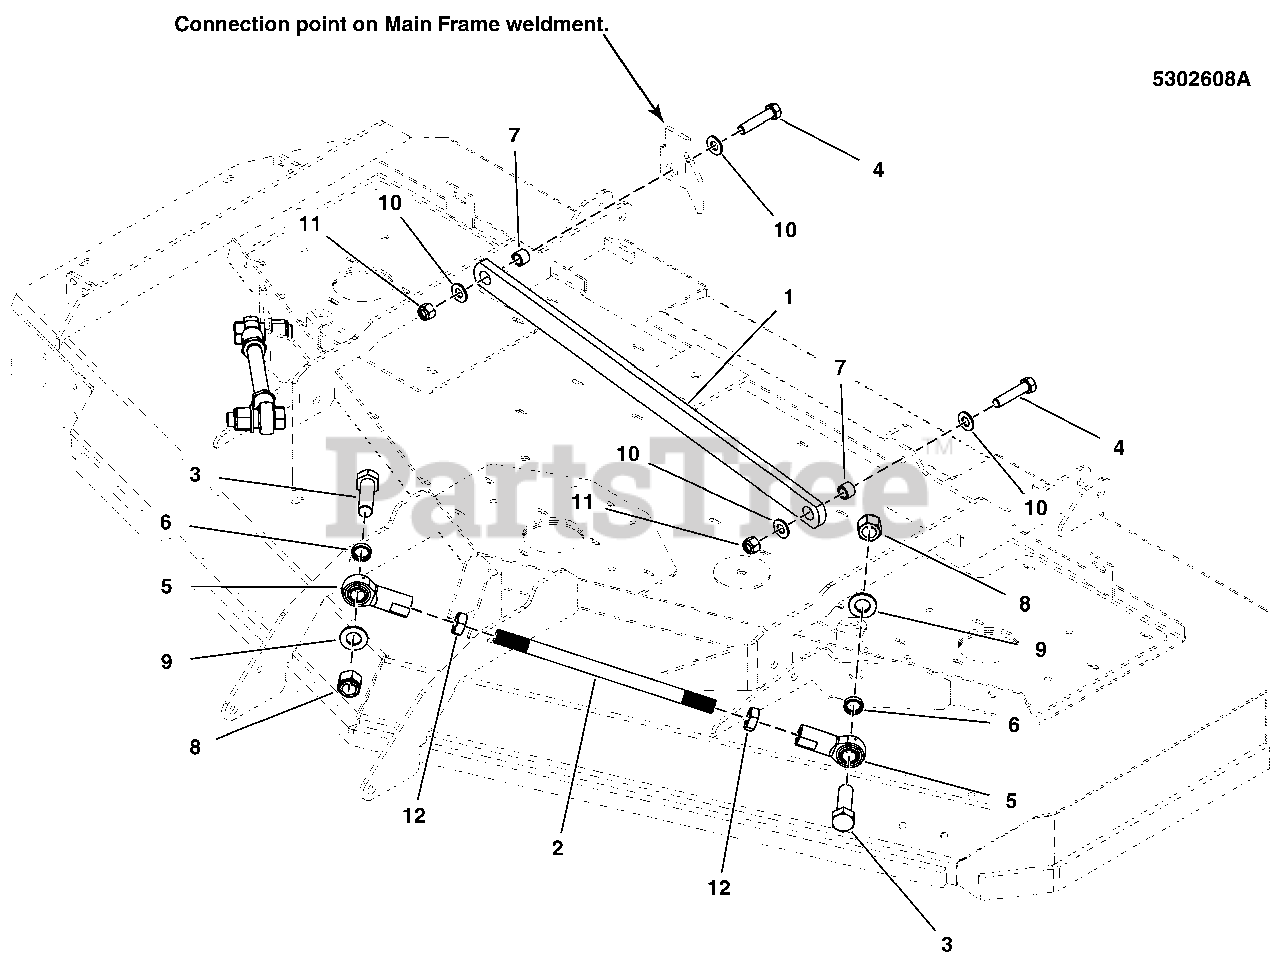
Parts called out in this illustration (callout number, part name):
1	BAR, PAN HARD, S200XT - RED
2	ROD, 3/4-16 X 12.31 - BLK
3	BOLT, 3/4-16 X 2-1/2 GD8 CZ
4	BOLT, 1/2-20 X 2-1/4 GD5 CZ
5	BALL JOINT, 3/4-16, FEMALE
6	SPACER, .76 X 1.00 X .25
7	SPACER, .51 X .75 X .56, PM, CZ
8	NUT, 3/4-16 HEX NYLON LOCK
9	WASHER, 3/4 SAE
10	WASHER, 1/2 SAE
11	NUT, Hex, Nylon Lock, 1/2-20
12	NUT, 3/4-16 HEX JAM
